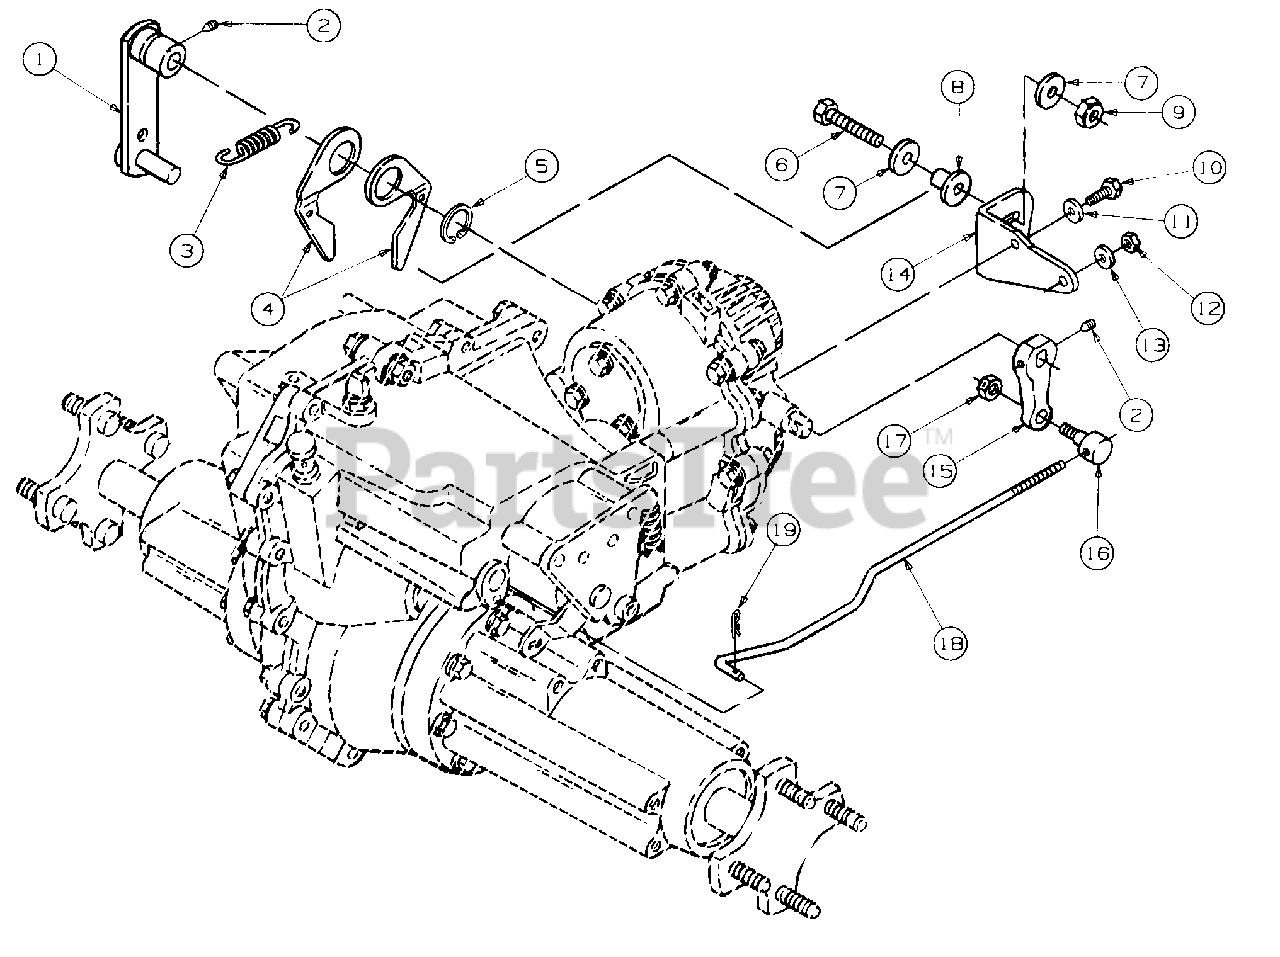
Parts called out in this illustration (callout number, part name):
1	Arm Assy, Control
2	Screw w/Patch, Set
3	Spring, Extension, .477 OD x 1.68 Lg
4	Arm, Neutral
5	Ring, Snap,.875 Shaft
6	Screw, Hex Cap, 1/4-20 x 1.25 Lg
7	Washer, Flat, .25 x .93 x .120 Thk
8	Spacer, Centering
9	Nut, Hex Top Lock, 1/4-20
10	Screw, Hex Cap, 5/16-18 x 4.0 Lg.
11	Washer, Lock, 5/16
12	Nut, Hex Top Lock, 1/4-20
13	Washer, Flat, .25 X .62 x .052 Thk
14	Bracket, 6-Speed Neutral
15	Arm, Clutch/Brake
17	Nut, Hex Center Lock Jam, 5/16-24
18	Rod, Shift Interlock
19	Pin, Internal Cotter
